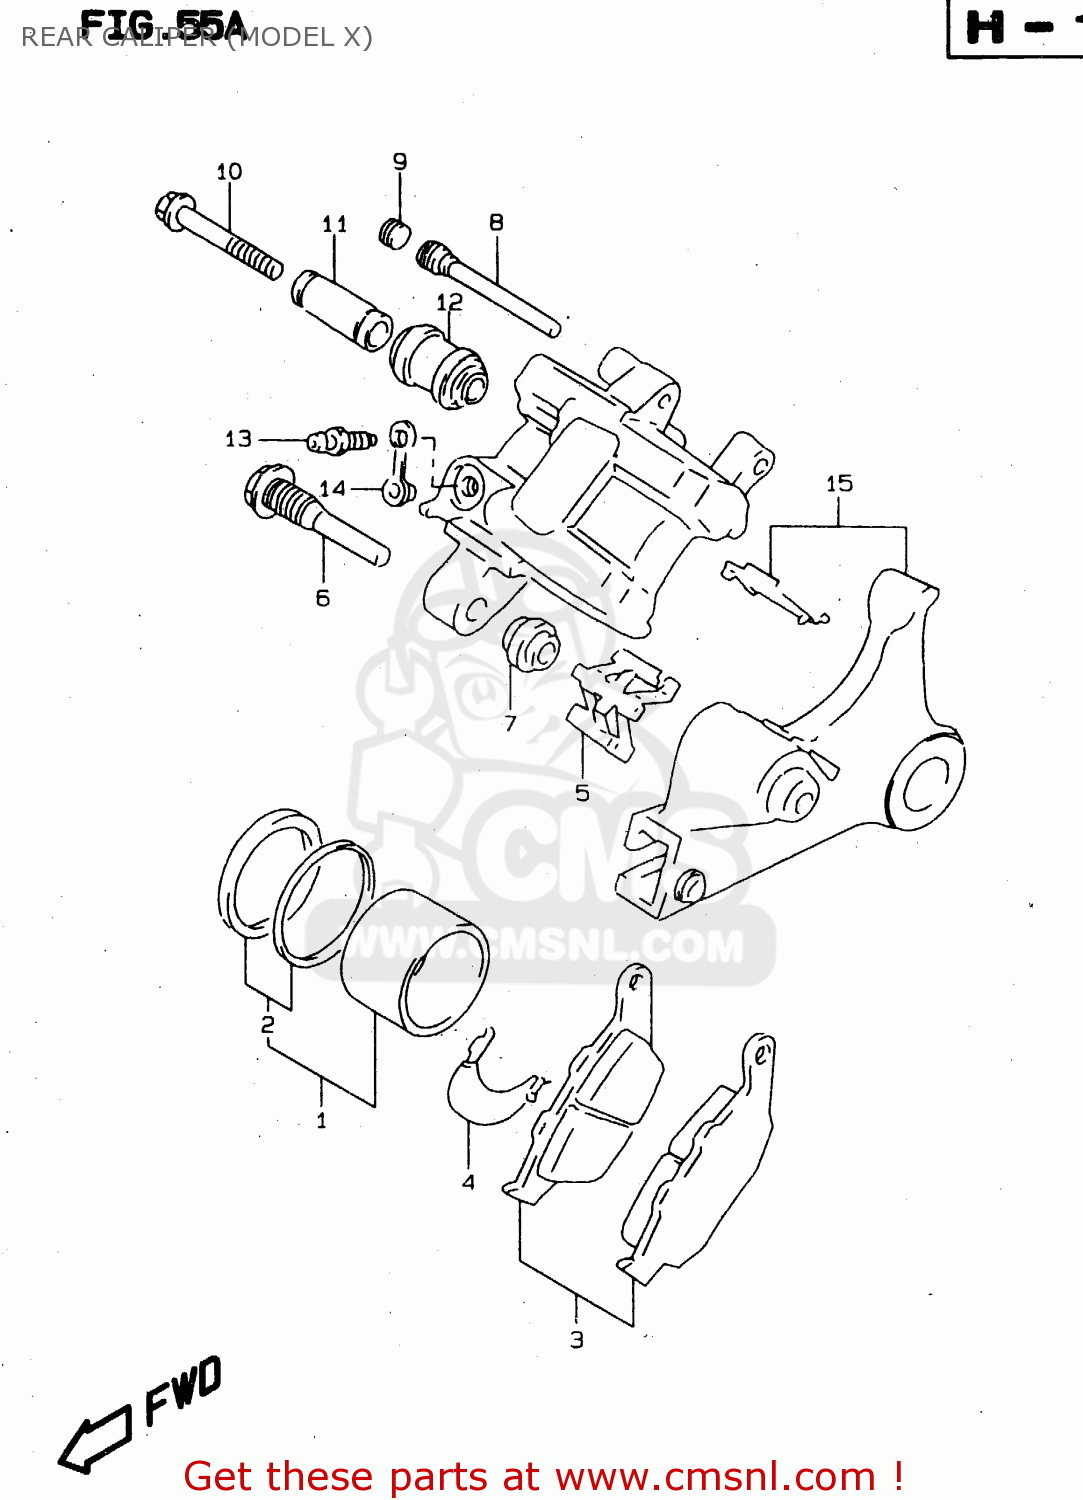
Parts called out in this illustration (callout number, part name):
1	PISTON SET
2	SEAL SET,PISTON
3	PAD SET (NAS)
4	SHIM
5	SPRING,PAD
6	BOLT
7	BOOT
8	PIN,HANGER
9	PLUG,PIN
10	BOLT
11	SLEEVE
12	BOOT,SLEEVE
13	BLEEDER
14	CAP,BLEEDER
15	BRACKET
